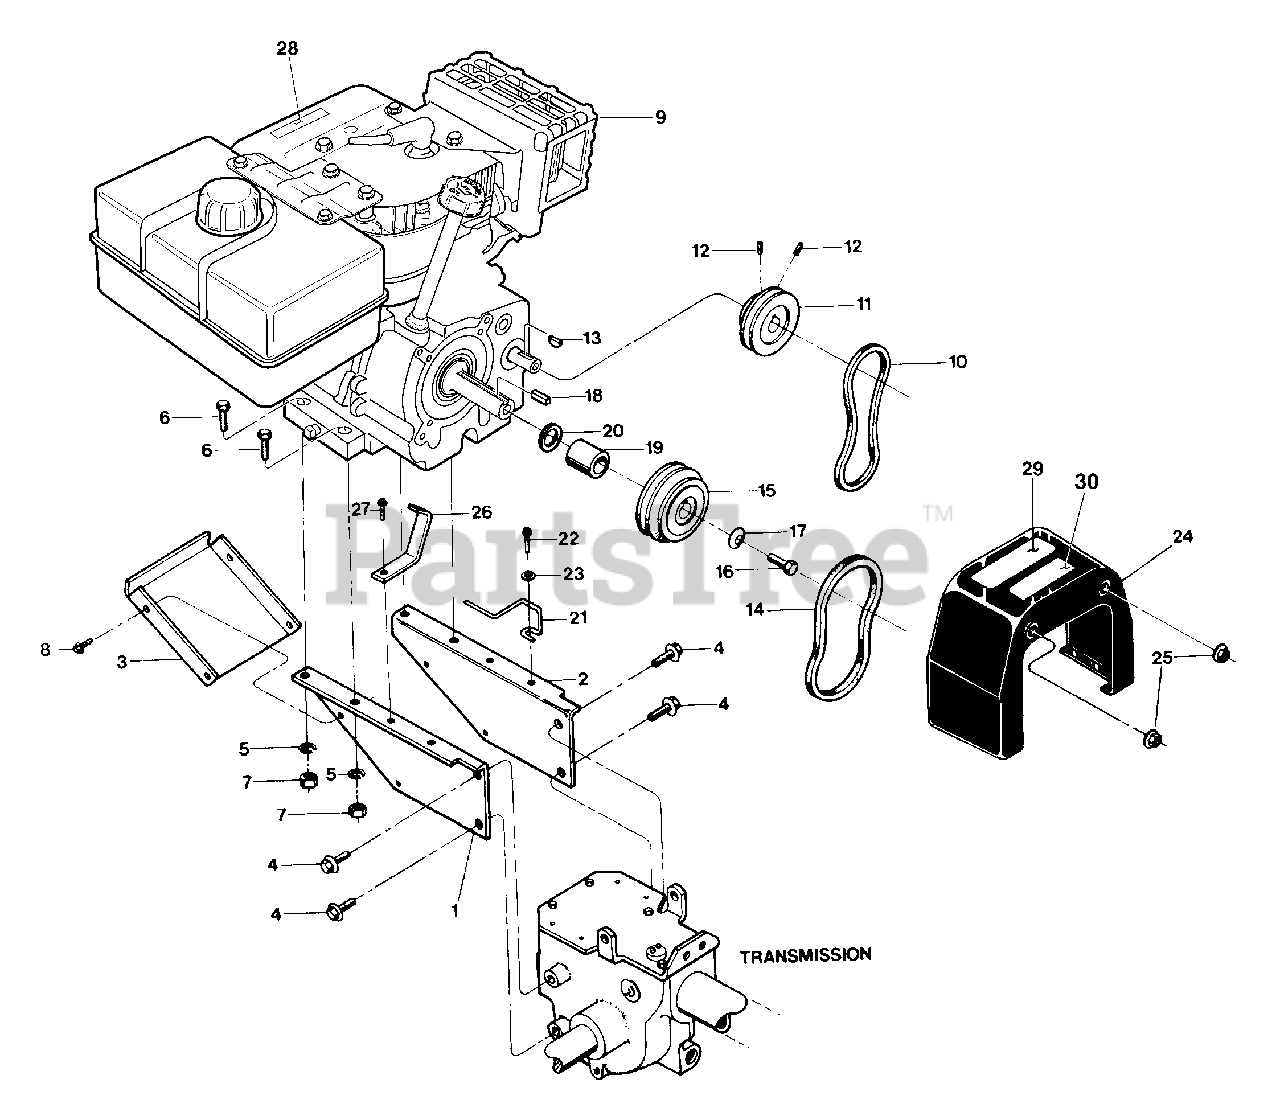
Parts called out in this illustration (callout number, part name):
1	Support bracket, left side
2	Support bracket, right side
3	Support bracket, front
4	Screw, flanged hex hd., 5/16-18 x 3/4
5	Lockwasher, 5/16"
6	Screw, hex hd., 5/16-18 x 3/4
7	Nut, hex hd., 5/16-18
8	Screw, self-tapping, hex hd., No.10-32 x 1/2
9	Tecumseh Engine, recoil start, electronic solid state ignition, 7 Horsepower
10	V-Belt, reverse
11	Reverse Pulley
12	Set Screw, socket head, 1/4-20 x 1/4
13	Key, Woodruff (#5)
14	V-Belt, forward
15	Forward Pulley
16	Screw, hex head, 3/8-24 x 1, Grade 5
17	Washer, disc spring
18	Key, 3/16 square x 1
20	Shim
21	Belt guide
22	Screw, hex head, 1/4-20 x 3/4, self tapping
23	Washer, flat, 1/4 S.A.E
24	Cover
25	Nut, Whiz Lock, 5/16-18
26	Belt Guide
27	Screw, flanged hex head, 1/4-20 x 1/2, self-tapping
28	Decal, Hot Surface/Belt Cover
29	Decal, Belt Cover
30	Decal, Belt Position
